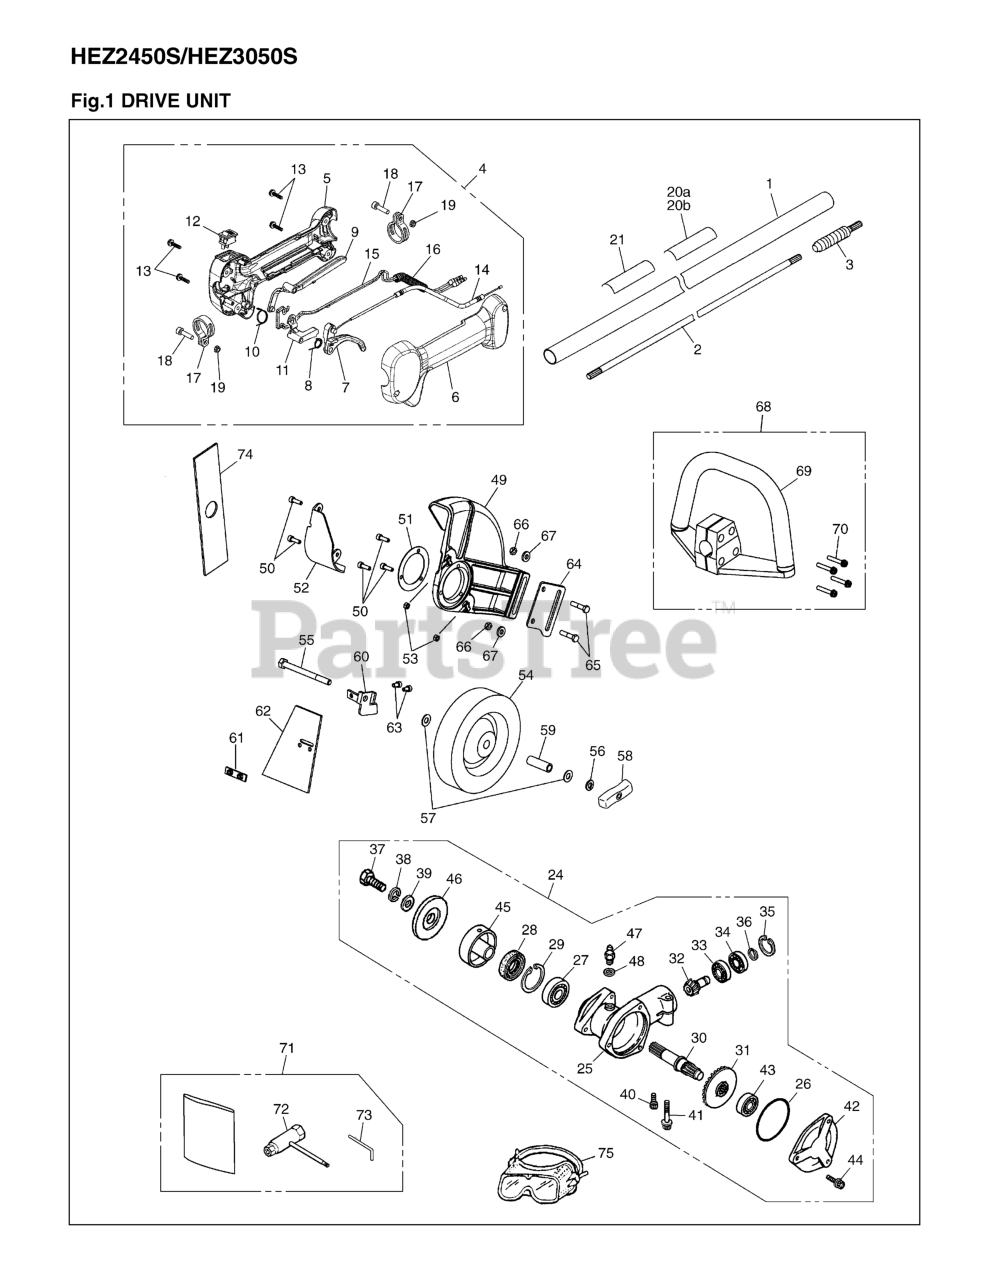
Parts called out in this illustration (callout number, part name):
1	PIPE COMP (RPLS 848A475820)
2	SHAFT
3	JOINT COMP
4	GRIP ASSY
7	LEVER, THROTTLE
8	SPRING, THROTTLE
9	LEVER SAFETY
11	LEVER JOINT
12	SWITCH
13	SCREW
14	CABLE COMP
15	CORD COMP
16	TUBE
18	BOLT TORX
20A	LABEL NAME
20B	LABEL NAME
21	LABEL, CAUTION
24	GEARCASE ASSY
25	GEARCASE
26	O-RING
28	SEAL
29	SNAP RING
30	SHAFT
31	GEAR
32	PINION
33	BEARING
34	BEARING
35	SNAP RING
36	SNAP RING
37	BOLT
38	WASHER
39	WASHER
40	BOLT
41	BOLT
42	COVER
43	BEARING
44	BOLT
45	HOLDER (A)
46	HOLDER (B)
47	FITTING, GREASE
48	WASHER, FITTING
49	GUARD
50	BOLT
51	PLATE
52	PROTECTOR
53	NUT
54	WHEEL
55	BOLT
56	WASHER, SPRING
57	WASHER
58	WING NUT
59	SLEEVE
60	BRACKET
63	BOLT
64	Main Bracket
65	BOLT
66	NUT
67	WASHER
68	HANDLE ASSY
69	HANDLE COMP
70	SCREW
71	TOOL-SET
72	SOCKET
73	BAR
75	GOGGLE
